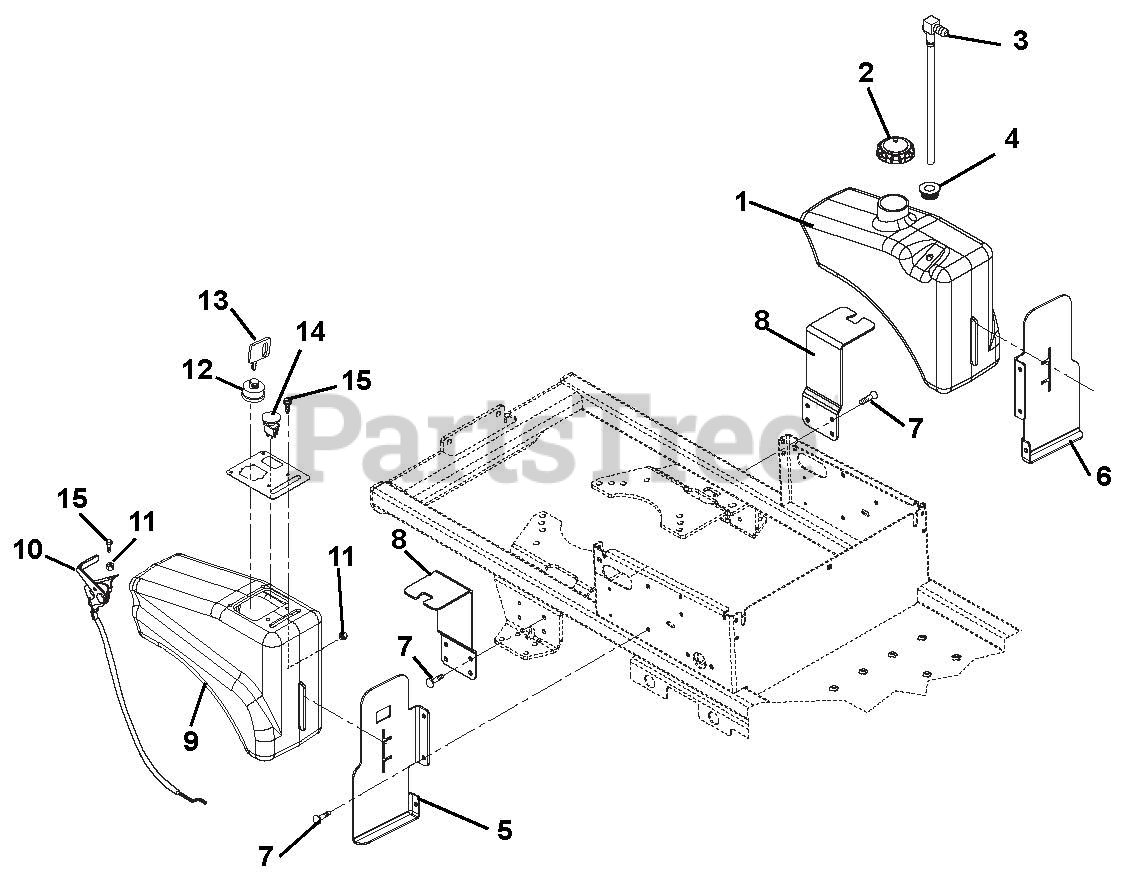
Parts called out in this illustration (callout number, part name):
1	Tank, Fender - Left Hand
2	Fuel Cap
3	Fitting, Tank
4	Bushing, Flange .375 x 1.062 x .625
5	Bracket, Fuel Tank RH
6	Bracket, Fuel Tank LH
7	Screw, Tapping .31-18 x .50
8	Mount, Fuel Tank
9	Tank, Fender - Right Hand
10	Cable, Throttle
11	Nut-Locking-Nylon 10-24 with Insert
12	Key Switch
13	Key, w/cap
14	Switch, Clutch
15	Screw-Machine 10-24 x .75 Hex Washer Head
16	Control Panel
